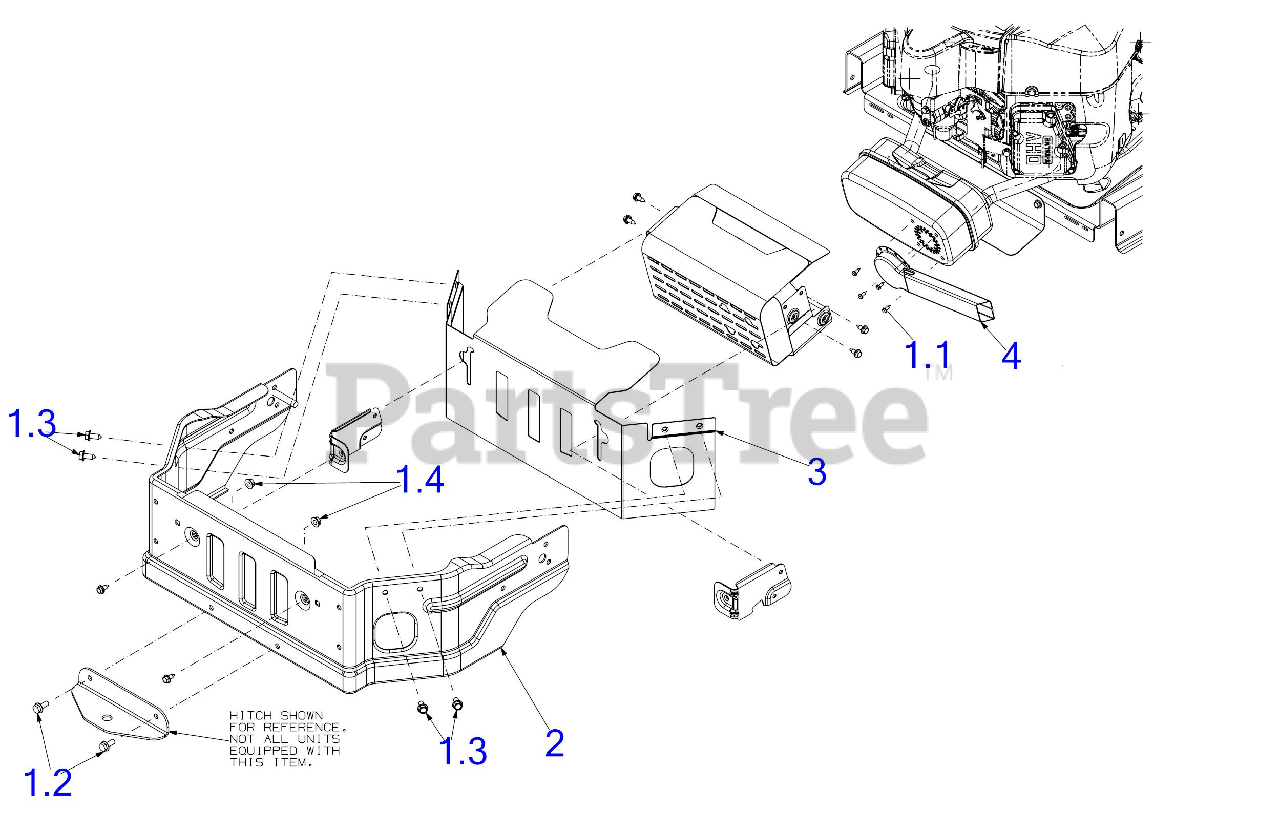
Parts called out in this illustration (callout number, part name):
1.1	HEX SCREW WASHER HD #8-18 x 0.500
1.2	SCREW 5/16-18
1.3	SCREW 5/16-18 x .750
1.4	HEX FLANGE NUT
3	MUFFLER BUMPER SHIELD
4	MUFFLER DEFLECTOR
